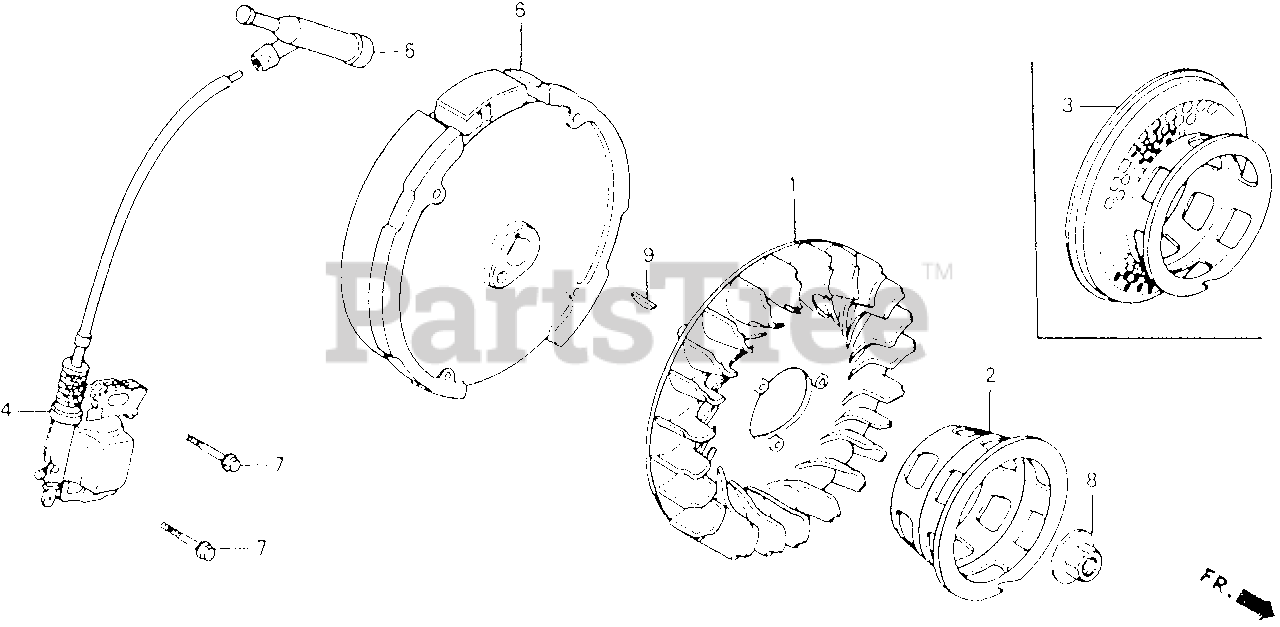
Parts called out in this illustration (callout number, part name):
1	FAN, COOLING
2	PULLEY, STARTER
4	COIL ASSY., IGNITION
5	CAP ASSY., NOISE SUPPRESSOR
6	FLYWHEEL
7	BOLT, FLANGE (6X28)
7	BOLT, FLANGE (6X25)
8	NUT, SPECIAL (14MM)
9	KEY, SPECIAL WOODRUFF (25X18)
